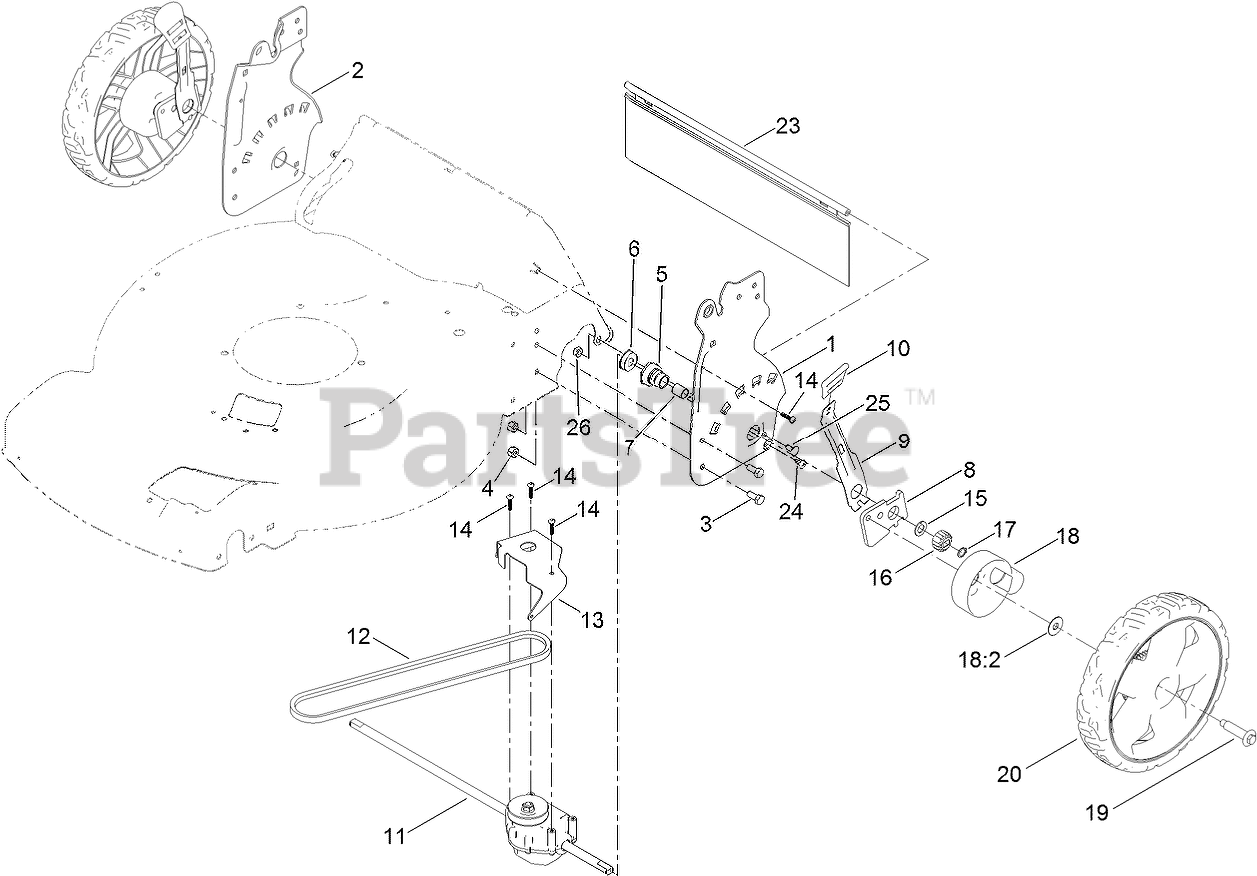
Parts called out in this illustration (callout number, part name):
1	PLATE-HOC, RWD (LH)
2	PLATE-HOC, RWD (RH)
3	SCREW-HH
4	NUT-LOCK, NI
5	RETAINER-BUSHING, HOC
6	BEARING-BALL
7	BUSHING-SLEEVE
8	ARM-PIVOT, REAR
9	ARM-SPRING
10	KNOB-HOC
11	TRANSMISSION
12	BELT-V
13	BRACKET-TRANSMISSION
14	SCREW-PLASTITE
15	WASHER-THRUST
16	GEAR-PINION, 15T
17	RING-RETAINING
18	GEAR COVER ASM
18:2	WASHER-STEPPED
19	BOLT-SHOULDER
20	WHEEL GEAR ASM
23	SHIELD-TRAILING
24	SCREW-PTH
25	SCREW-CARR
26	NUT-LOCK, NI
